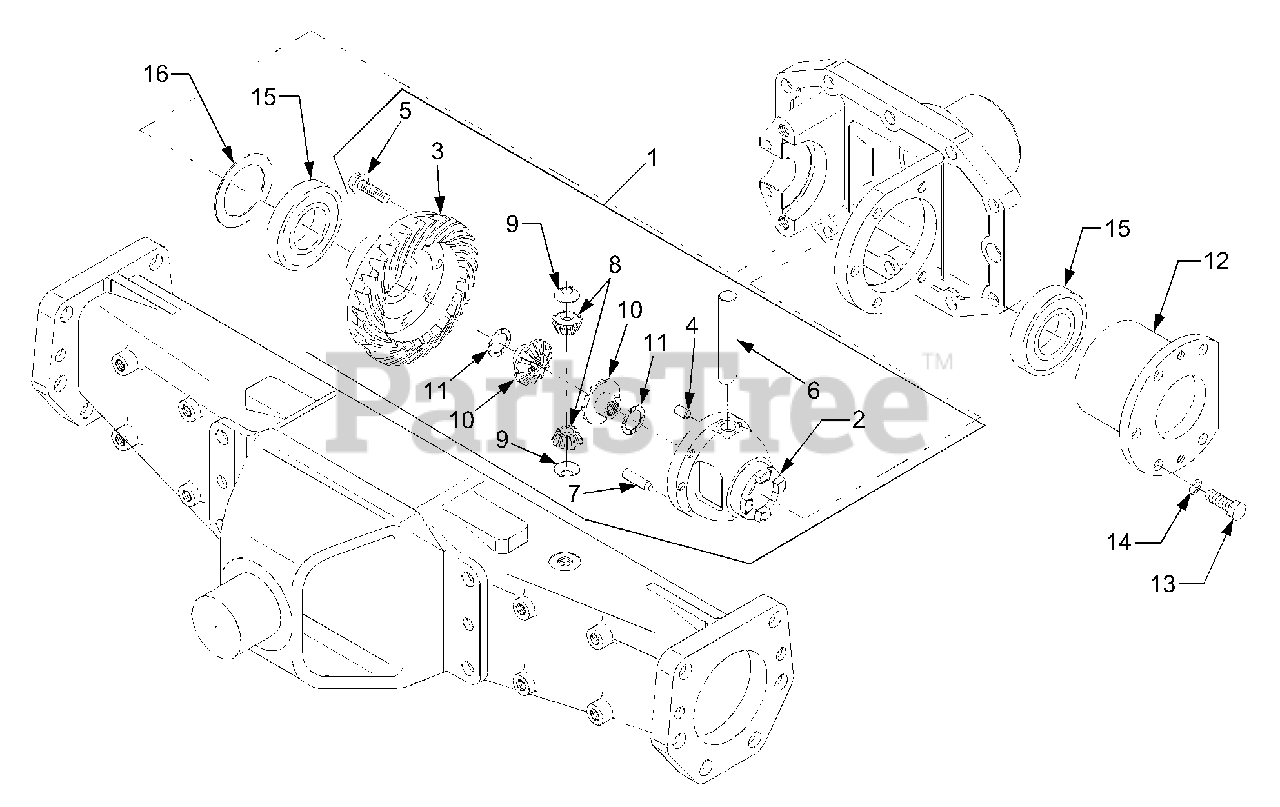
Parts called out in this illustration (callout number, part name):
1	Front Differential Ass'y
2	Case, Front Differential
3	Gear, 27 Bevel
4	Pin, Straight
6	Shaft, Differential Pinion
7	Pin, Straight
8	Pinion, Differential
9	Washer, Differential Side
10	Gear, Differential Side
12	Support, Front Diff. Bearing
14	Washer, Spring
15	Bearing, Ball
